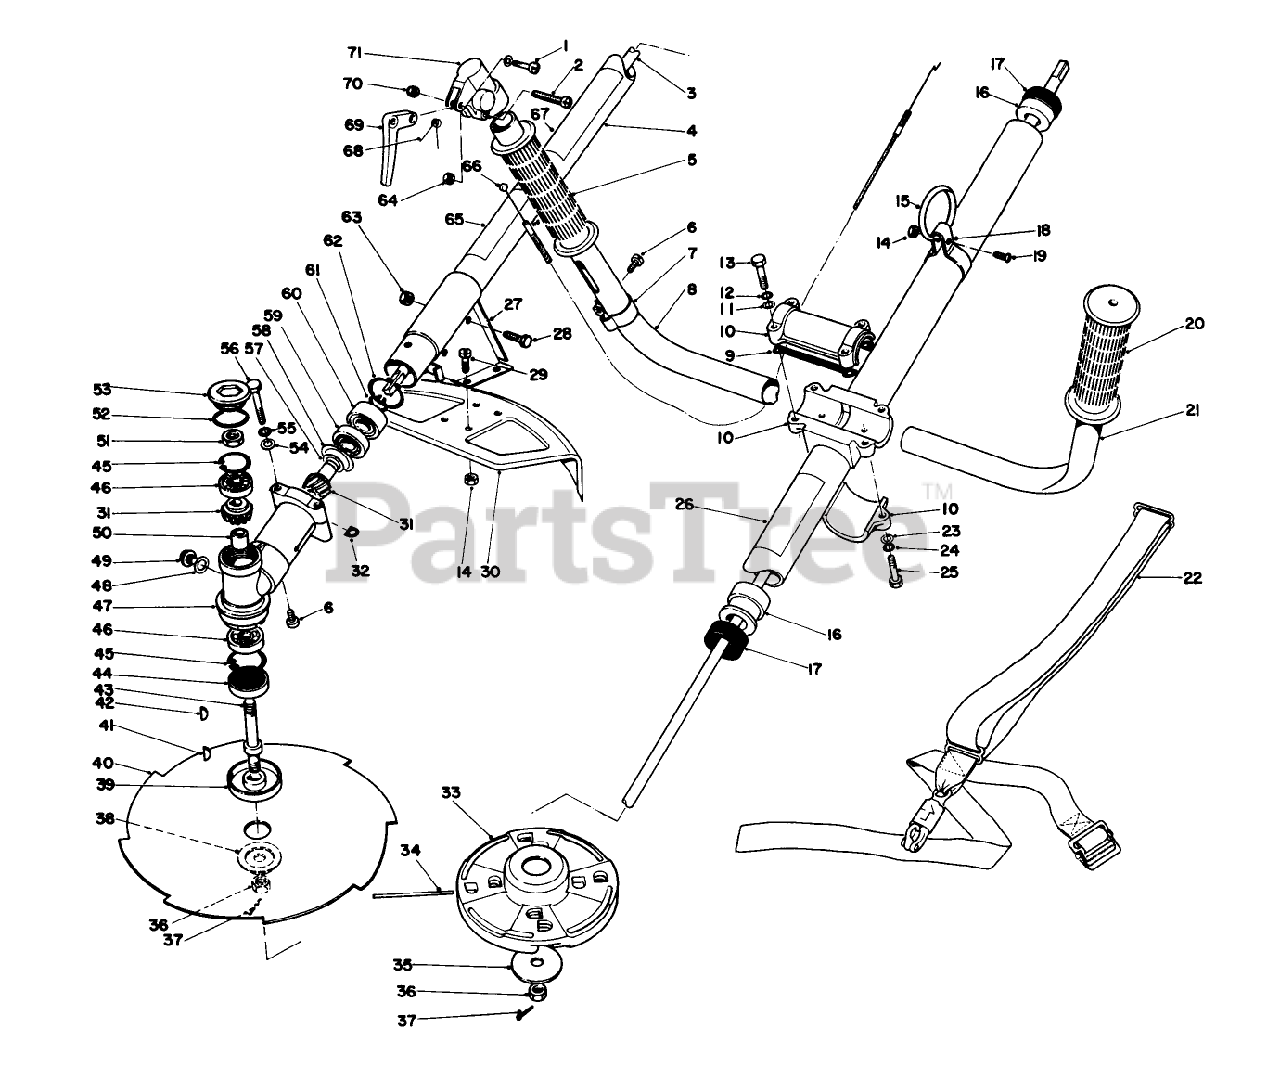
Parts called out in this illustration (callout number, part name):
9	Shim Washer
14	NUT-LOCK, NI
15	RING-HARNESS
17	Bushing
18	HARNESS CLAMP
19	SCREW-SRH
28	SCREW-HH
29	SCREW-PPH
34	LINE PACK (100)
35	Washer
37	1/16 X 1 LG COTTER PIN
38	BLADE ADAPTER KIT
63	NUT-LOCK, NI
